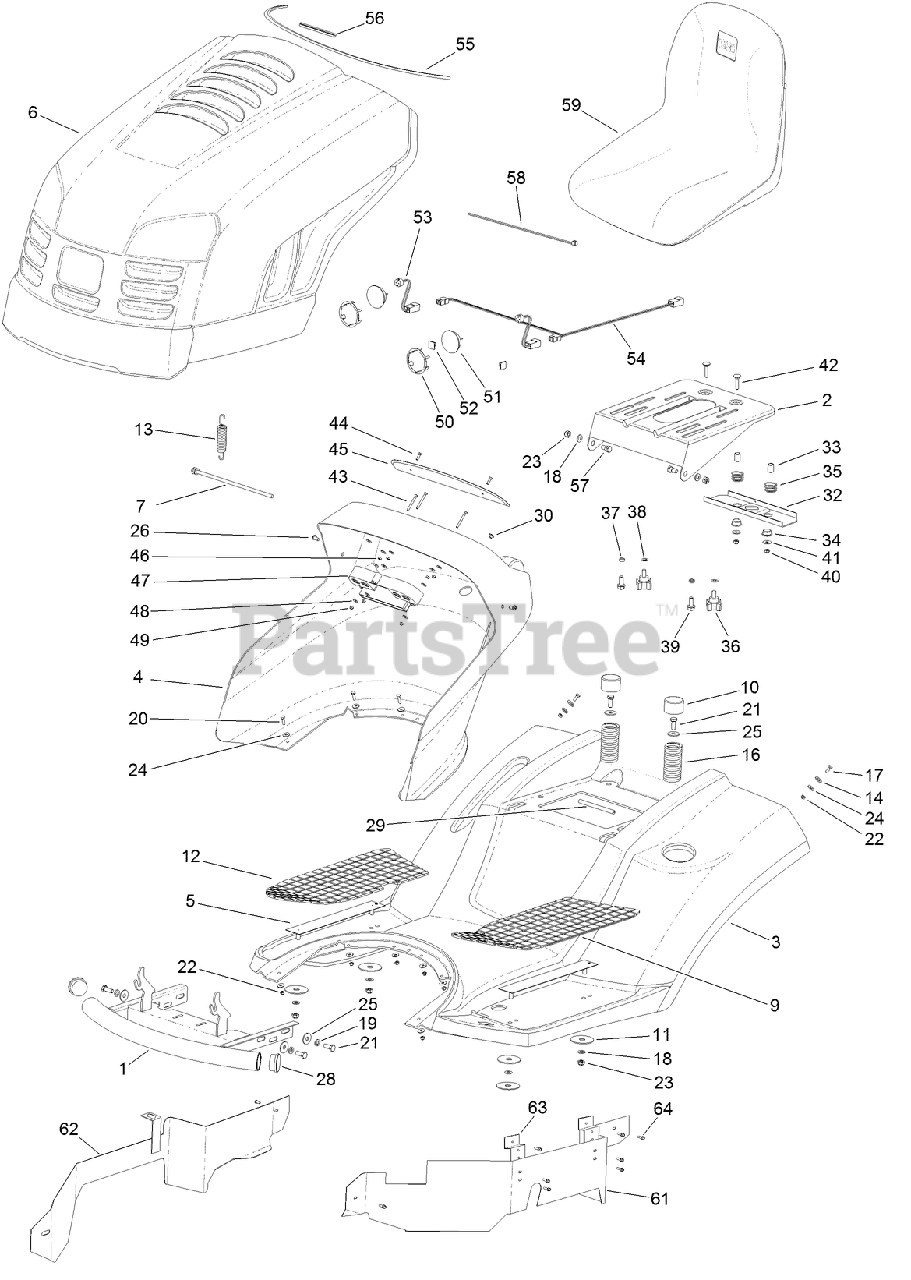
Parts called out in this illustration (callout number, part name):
1	BUMPER
2	BRACKET-SUPPORT, SEAT
3	FENDER-REAR
4	PANEL-DASH
5	HOLDER
6	HOOD ASM
7	HOLDER-SPRING
9	MAT-FOOT, LH
10	CAP-HUB
11	WASHER-RUBBER
12	MAT-FOOT, RH
13	SPRING-HOOD
14	WASHER-RUBBER
16	SPRING-SEAT
18	WASHER-PLAIN
19	WASHER-SPRING
21	SCREW-HH
22	NUT-LOCK
23	NUT-LOCK, NI
24	WASHER-FLAT
25	WASHER-PLAIN
26	SCREW-HH
29	TRIM-RUBBER
32	BRACKET
33	SPACER-SPLIT
34	BUSHING
35	SEAT-SPRING
36	KNOB-ADJUST
37	SPACER
38	WASHER-SPRING
39	SCREW-SUPPORT, SEAT
40	NUT-LOCK
41	WASHER-FLAT
42	SCREW-CARR
45	LENS-DASH
47	HOUSING-LIGHT, INDICATOR
48	WASHER
49	NUT-HEX
50	SOCKET-LAMP
51	BULB-LIGHT
52	CLIP-NYLON
53	HARNESS-WIRING, LIGHT BULB
54	HARNESS-WIRING, LIGHT
55	TRIM-RUBBER, HOOD
56	GASKET-FOAM
57	SCREW-SUPPORT, SEAT
58	TIE-CABLE
59	SEAT ASM
61	COVER,-LEFT
62	COVER-RIGHT
63	HOLDER
64	SCREW-TAP
